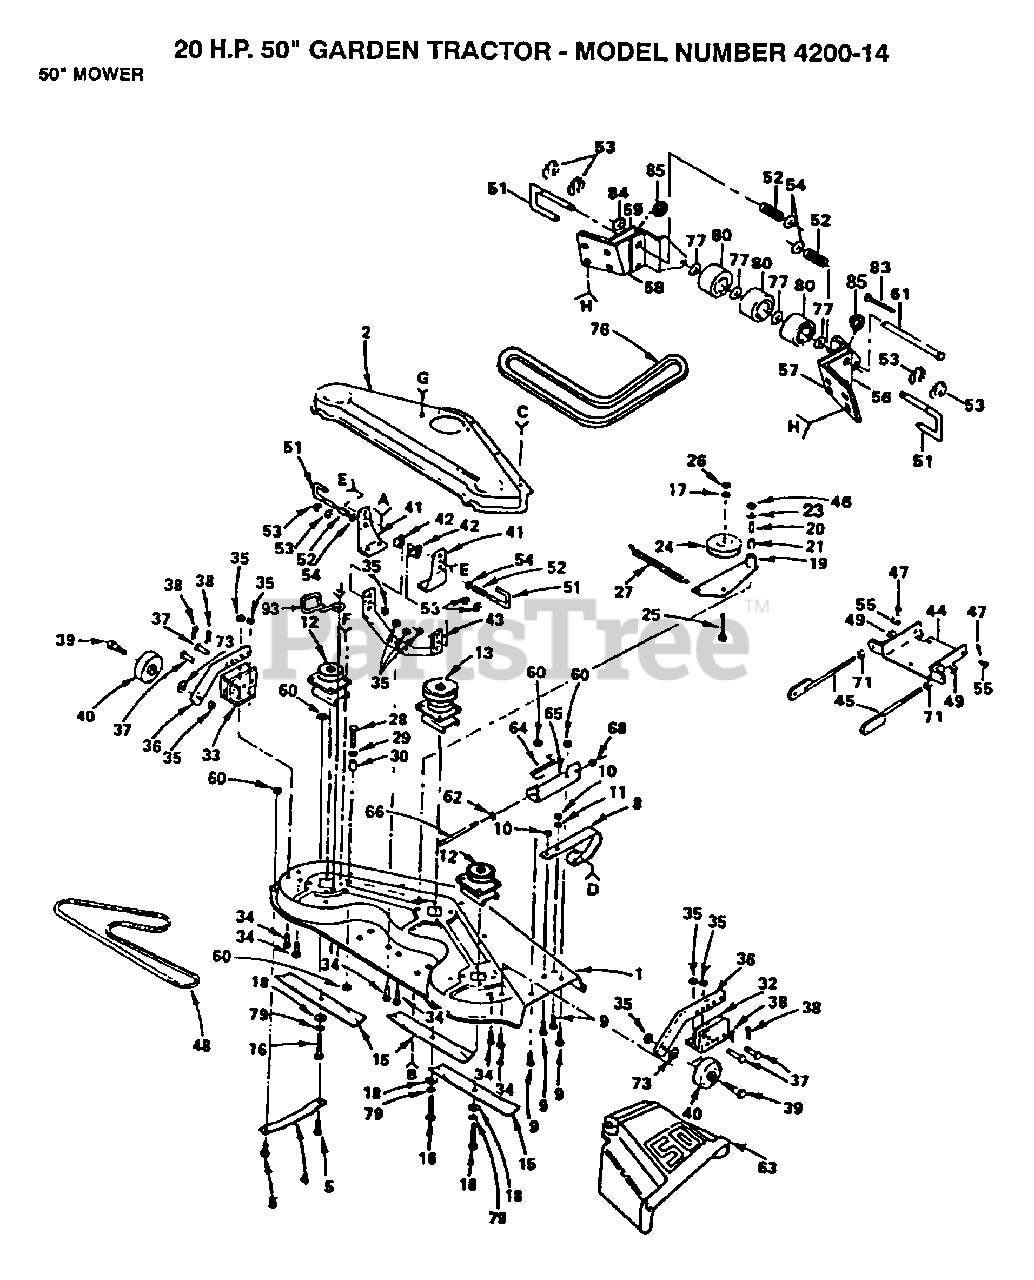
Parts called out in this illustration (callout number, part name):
2	CVR DRIVE DECK
3	SCREW LT
4	RUNNER-LH M
5	BOLT
6	LOCKWASHER
7	NUT.HEX.5/16-18
9	BOLT
14	SCREW
15	"BLADE.50""STD.LIFT"
16	BOLT.3/8-24X1-1/2
17	LOCKWASHER
18	WASHER
19	ARM ASSY GT
22	BOLT
24	IDLER-FLAT T
26	NUT.HEX.3/8-16UNC
27	SPRING T
28	BOLT
29	WASHER M
30	SPACER SPLIT LT
31	WASHER
32	GUAGE WHL BRKT GT
33	GUAGE WHL BRKT GT
34	BOLT
36	GUAGE WHL BAR GT
39	BOLT M
40	WHEEL.GAGE.BLK.PL
41	SUSP BRKT GT
42	SPACER GT
43	SUSP BRACE GT
45	BRACKET.SUSPEN.AS
46	JAM NUT TI
47	RETAINER.SPRING
48	V-BELT M
49	NUT LTV
50	BOLT
51	RELEASE PIN GT
52	SPRING M
53	KLIP RING
55	CLEVIS PIN GT
56	BRACKET T
57	BRACKET T
58	BRACKET T
59	BRACKET T
61	PIVOT PIN T
62	WASHER
63	DEFLECTOR
66	ROD-HINGE T
68	NUT PUSH M
71	NUT
73	WASHER
74	BOLT
76	BELT-V.93.5.MWR
77	WASHER T
80	ROLLER T
83	COTTER PIN
85	SPACER T
93	BELT RETIANER
